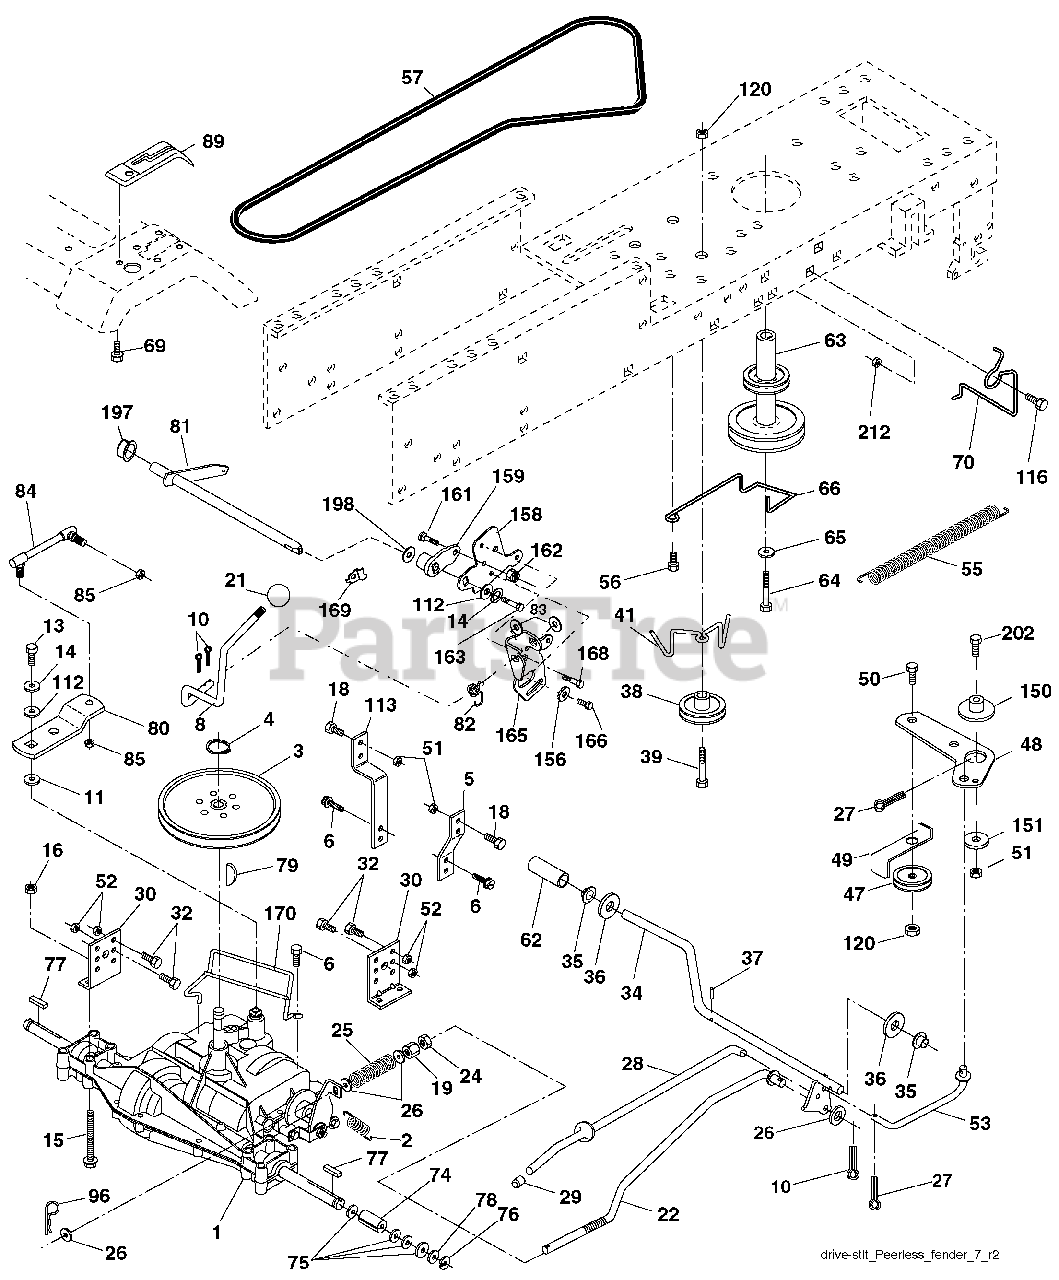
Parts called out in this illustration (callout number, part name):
1	Transaxle Peerless 205-544C (Internal Parts Not Available)
2	Spring Return Brake
3	Pulley Transaxle 18" Tires
4	Ring Retainer # 5100-62
5	Strap Torque 30 Degrees RH
6	Screw 5/16-18 x 3/4
8	Rod Shifter Blk
10	Pin Cotter 1/8 x 1 Cad
11	Washer Plate Shf 388 Sq Hole
13	Bolt 1/4-28 unf Gr. 8 w/Patch
14	Washer Lock Hvy Helical 1/4
15	Bolt Hex Flghd 5/16-18 Gr. 5
16	Nut 5/16-18
18	Bolt Fin Hex 3/8-16 unc x 1 Gr. 5
19	Nut Lock Hex w/Ins 3/8-16 unc
21	Knob
22	Rod Brake LT
24	Nut Hex Jam 3/8-16 unc
25	Spring Rod Brake 2 00 Zinc
26	Washer 13/32 x 13/16 x 16 Ga.
27	Pin Cotter 1/8 x 3/4 Cad
28	Rod Brake Parking LT/YT
29	Cap Brake Parking Black
30	Bracket Transmission
32	Bolt Fin Hex 5/16-18 x 3/4
34	Shaft Asm Pedal Foot Nibbed
35	Bearing Nylon Blk 629 Id
36	Washer 21/32 x 1 x 16 Ga.
37	Pin Roll 3/16 x 1"
38	Pulley Composite Flat
39	Bolt 3/8-16 x 2-3/4
41	Keeper Belt Idler
47	Pulley Idler V Groove Plastic
48	Bellcrank Clutch Grnd Drv STL
49	Retainer Belt Style Spring
50	Bolt Carr Sh 3/8-16 x 1-1/2 Gr. 5
51	Nut Crownlock 3/8-16 unc
52	Nut Crownlock 5/16-18 unc
53	Link Clutch
55	Spring Return Clutch 6 75
56	Screw 3/8-16 x 1-1/4
57	V-Belt Traction Drive 95.25
62	Cover Pedal Blk Round
63	Engine Pulley LT/YT
64	Bolt Hex 7/16-20 x 4 Gr. 5
65	Washer Lock Hvy Hlcl Spr 7/16
66	Keeper Belt Engine
69	Screw 1/4 x 1/2 unc
70	Guide Belt Mower Drive RH
74	Spacer Axle
75	Washer 25/32 x 1 1/4 x 16 Ga.
76	ring #5133-75
77	Key Square 2 0 x 1845/ 1865
78	Washer 25/32 x 1-5/8 x 16 Ga.
79	Key Woodruff
80	Arm Shift Transaxle
81	Shaft Asm Cross Taper
82	Spring Torsion Shift
83	Washer 17/32 x 3/4 x 16 Ga.
84	Link Transaxle
85	Nut Lock Center 1/4-28
89	Console Shift
96	Retainer Spring 1"
112	Washer 9/32 x 3/4 x 10 Ga.
113	Strap Torque 90 Degrees LH
116	Bolt Rdhd Sq Neck 3/8-16 x 1
120	Nut Lock Flg 3/8-16
150	Spacer Retainer Lt
151	Washer 13/32 x 2 x 10 Ga.
156	Washer Srrrtd 5/16 ID x 1.0 x .125
158	Bracket Shift Mount
159	Hub Shift
161	Bolt 1/4-20 x 3/4 Gr. 5
162	Nut Crownlock 1/4-20 unc
163	Bolt Hex Fin 1/4-20 unc x 1 Gr. 5
165	Bracket Pivot Lever
166	Screw 5/16-18 x 5/8
168	Bolt Shoulder 5/16-18 x .561
169	Plate Fastening
170	Keeper, Belt Transaxle
197	Nyliner Snap-In 5/8
198	Washer Nylon
202	Bolt Carr Sh 3/8-16 x 1-3/4 Gr. 5
212	Nut Hex Flg Lock
